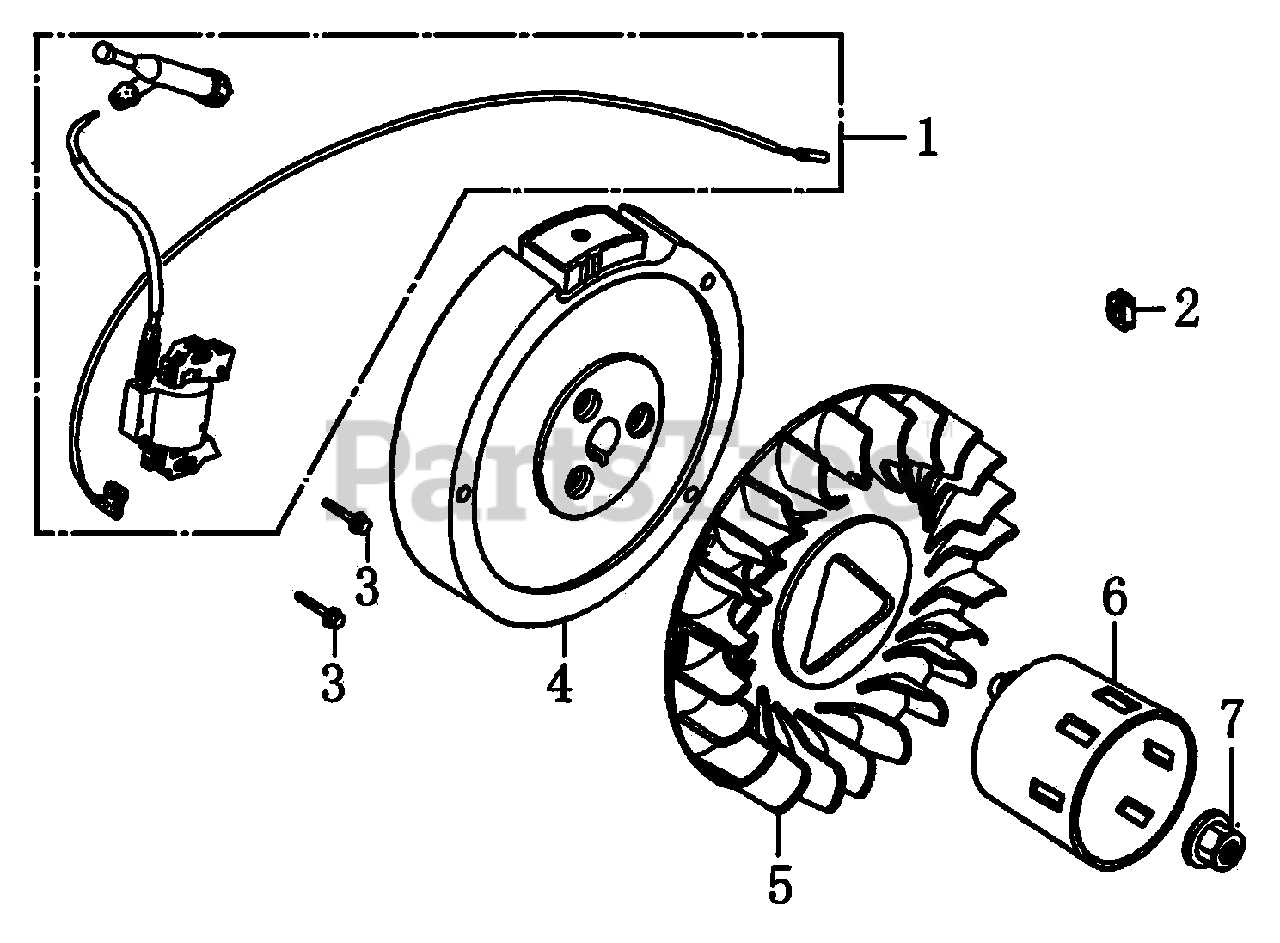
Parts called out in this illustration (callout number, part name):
1	COIL ASSY., IGNITION
2	GROMMET, CORD
3	BOLT, FLANGE,M6X25
4	FLYWHEEL COMP
5	FAN, COOLING
6	PULLEY, STARTER
7	NUT SPECIAL, 16MM
